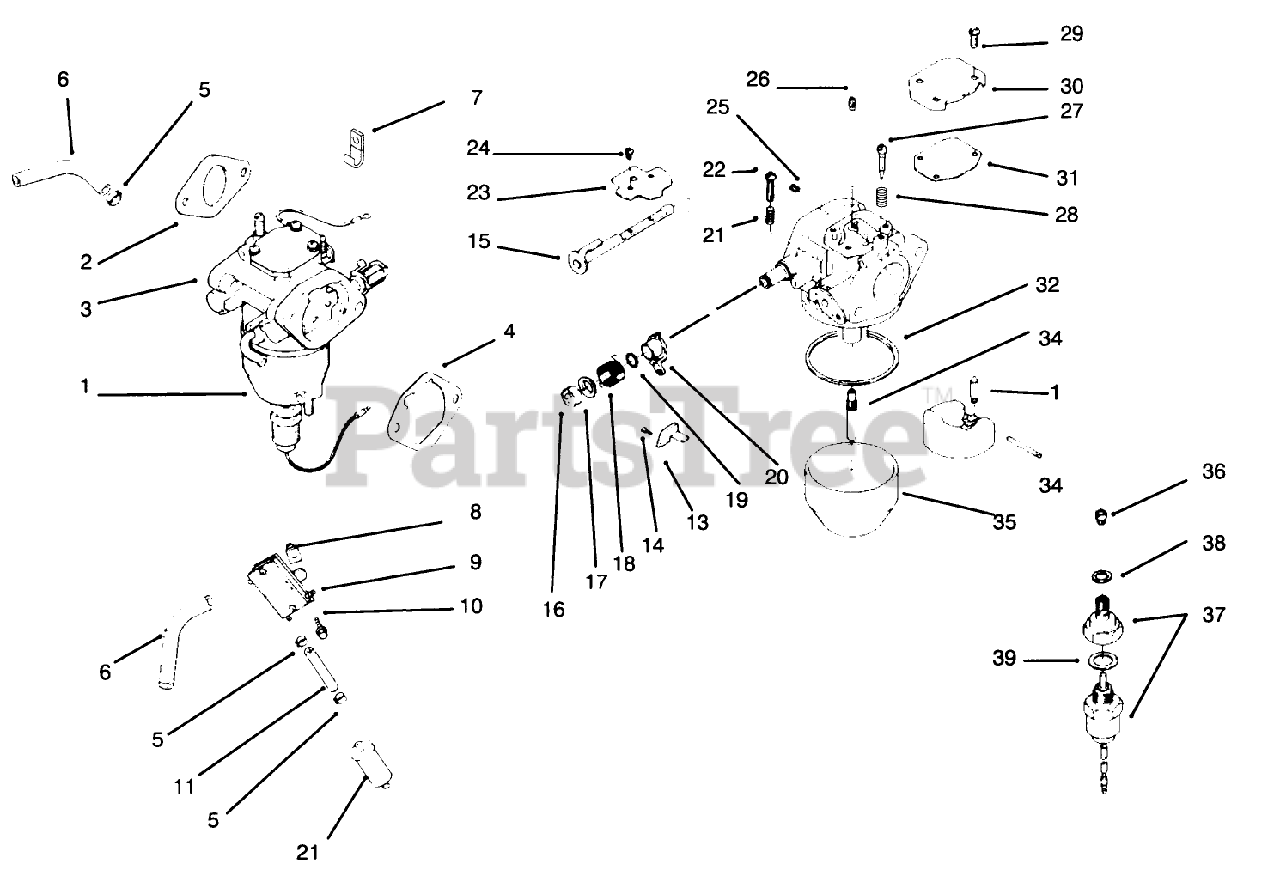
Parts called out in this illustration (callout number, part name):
1	Kit-Carburetor (Incl. Ref. #2-4)
2	Kit-Carburetor
3	Carburetor (Ref. Only) (Inc. Ref. 15-39)
4	Gasket-A/C Base
5	Clamp
6	Line-Fuel 12"
7	Clamp
8	Nut
9	Pump-Fuel
10	Screw
11	Line-Fuel
12	Filter-Fuel
13	Bracket-Throttle Stop
14	Screw
15	Shaft-Choke
16	Washer
17	Collar-Coke
18	Spring-Choke Return
19	Ring-Choke Lever
20	Lever-Choke
21	Sprin-Throttle Screw
22	Screw-Throttle Adjust
23	Valve-Choke
24	Screw
25	Jet-Air Bleed
26	Jet-Slow
27	Screw
28	Spring-idler Screw
29	Screw
30	Cover-Passage
31	Gasket-PassageCover
32	Gasket-FloatChamber
33	Kit-Float Repair
34	Nozzle-Main
35	Chamber-Float
36	Jet-Main
37	Kit-Solenoid Valve (Incl. Ref. #38-39)
38	Gasket-ChamberScrew
39	Gasket-Solenoid
